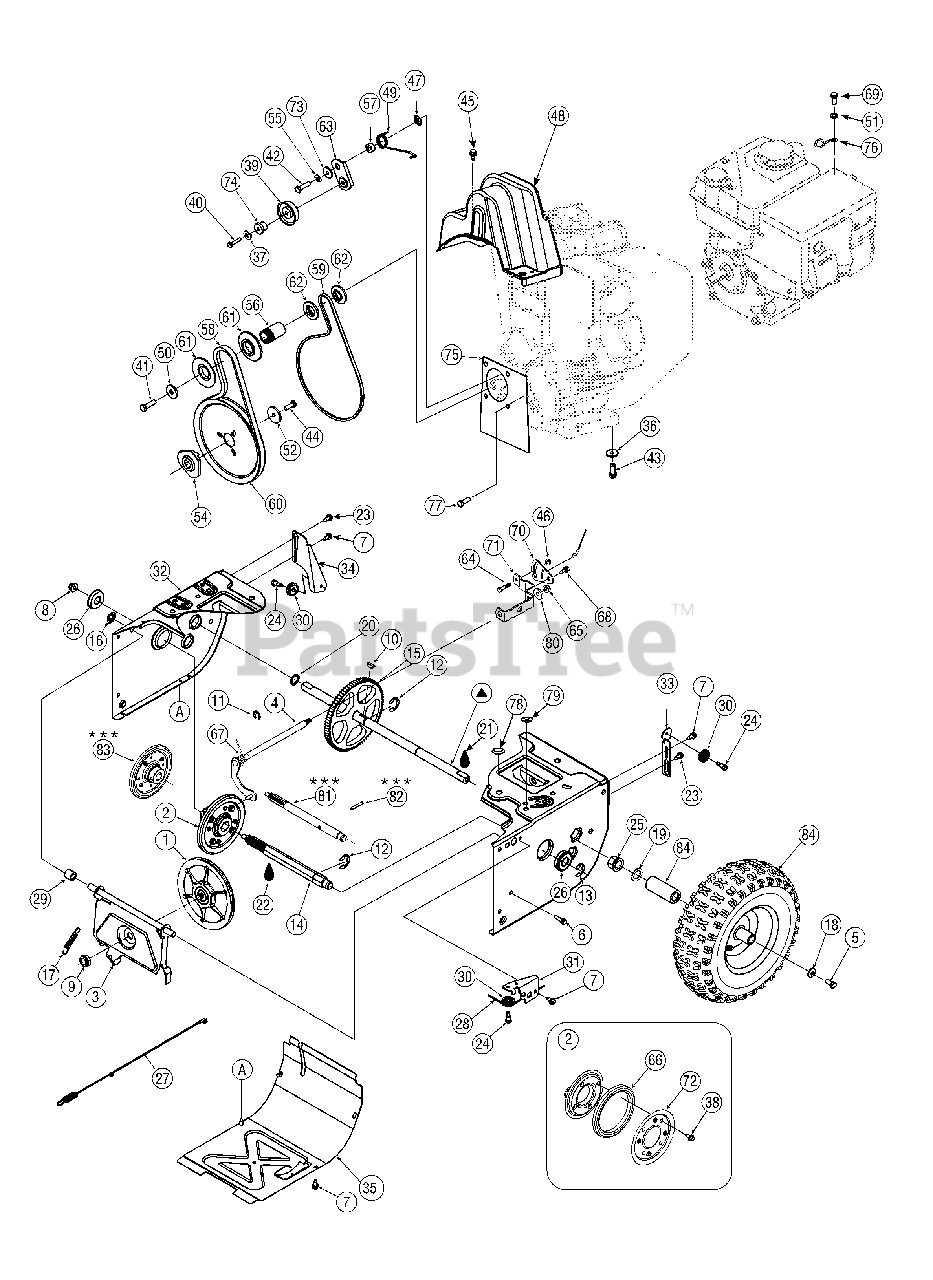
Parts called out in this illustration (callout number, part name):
1	Friction Wheel Disc Assembly
2	Friction Wheel Ass’y, Bearing 5.5 OD
4	Shift Rod Ass’y
5	Hex L-Bolt 5/16-24 x .75 Gr. 5
6	Hex Bolt 1/4-20 x 1.00
7	Hex Wash Hd TT Scr. 1/4-20 x .625
8	Flange Lock-Nut 3/8-16 Gr. F Nylon
9	Jam L-Nut 5/8-18
10	#9 HI-Pro Key 3/16 x 3/4 Dia HT
11	Retaining Ring
12	Retainer Ring
13	"E" Ring
14	Hex Shaft .8125 - 7 tooth
15	Gear - 80 Tooth
16	Cap Speed Nut 1/4 Rod
17	Extension Spring 3/8 OD x 2.50
18	Cupped Washer .345 ID x .88 OD x .060
19	Flat Washer .79 ID x 1.25 OD x .06
20	Flat Washer .75 x 1.00 x .06
21	Grease
22	Rust Preventative Oil
23	Shoulder Screw .373 x .105:TT 1/4-20
24	Hex Shld.Scr.1/4-28 x .375
25	Hex. Flange Bearing.751" ID
26	Ball Bearing w/snap ring
27	Drive Clutch Cable 44.83" Lg.
28	Auger Clutch Cable 47.23" Lg.
29	Spacer .513 ID x 1.0
30	Cable Guide Roller
31	Auger Cable Guide Bracket
32	Frame - Majestic Orange
33	Guide Bracket - Auger Cable
34	Guide Bracket - Drive Cable
35	Frame Cover - Majestic Orange
36	Flat Washer .38 x 1.38 x .125 (Rear left hole)
37	L-Wash 1/4 ID
38	Hex Wash. Hd. TT Scr. 1/4-14 x .625
39	Idler Pulley Assembly 1.917 OD
40	Hex Screw 1/4-20 x 1.25
41	Hex Screw 3/8-24 x 1.25
42	Hex Hd Cap Scr. 5/16-24 x 1.25 Gr. 5
43	Hex Wash HD Tap Scr 3/8-16 x .88
44	Hex Bolt 5/16-24 x 0.875
45	Hex Wash Hd TT Scr. 1/4-20 x .625
46	Hex L-Flanged Nut 1/4-20 Gr. F Nylon
47	Push Nut
48	Belt Cover (w/side chute control)
48	Belt Cover (w/2 & 4 way chute control)
49	Torsion Spring .850 ID x .354" Lg.
50	Flat Washer .40 ID x 1.25 OD x .160
51	Flat Washer .330 ID x .630 OD x .0635
52	Flat Washer .34 x 1.50 x .150
54	Pulley Adapter
55	Lockwasher 5/16
56	Spacer .875 ID x 1.185 OD
57	Spacer .340 x .750 x .360" Lg.
58	Belt .5 x 35.0" Lg.
59	Belt 3/8 x 34.4" Lg.
61	Pulley Half
62	Pulley Half 3/8 V x 1.71 OD
63	Wheel Drive Idler Bracket
64	Hex Bolt 1/4-20 x .62 Gr. 5
65	Flange Locknut 5/16-18 Gr. F, Nylon
66	Friction Wheel Rubber
67	Torsion Spring .750 ID x .968" Lg.
68	Shoulder Screw .373 x .105:TT 1/4-20
69	Hex. Hd. Cap Scr. M8-1.25:20 Gr. 8
70	Pivot Bracket
71	Shift Bracket
72	Friction Plate
73	Shld. Spacer .3175 x .5 x .1025
75	Cover Plate (optional)
76	Cable Control Wire
77	Shoulder Screw .50 x .145: 5/16-24
80	Flat Washer .469 x .875 x .105
81	Shaft .75" Dia. 7 tooth
82	Spring Pin .25 dia. x 2.50
83	Friction Wheel Ass’y
84	Wheel Ass'y 13 x 4 Snow Hog
